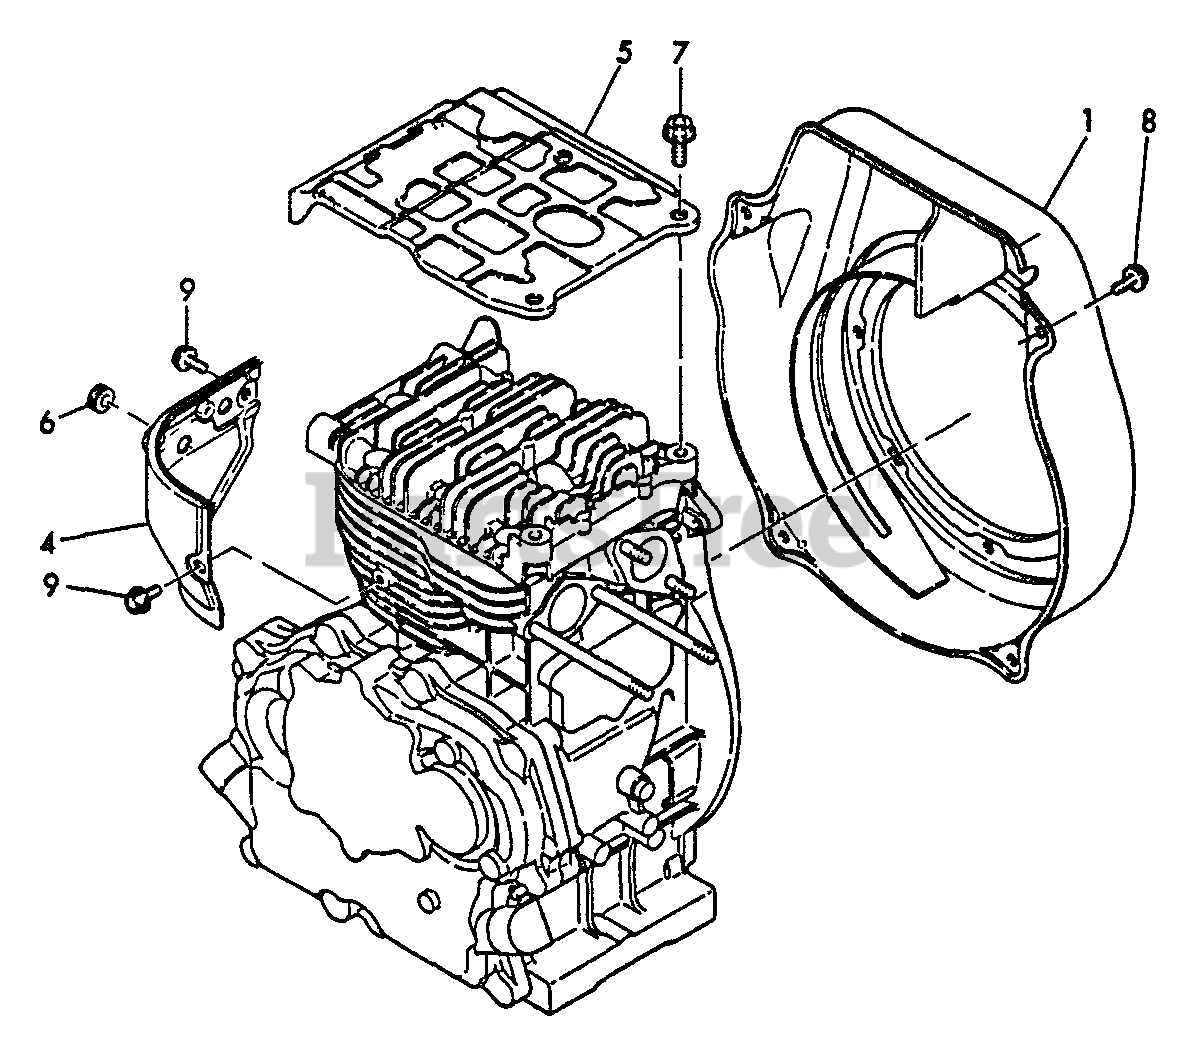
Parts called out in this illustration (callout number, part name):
1	COVER, FAN - INNER
4	SHIELD, CYLINDER
5	COVER, HEAD
6	GROMMET
7	BOLT - 8×20 -- PLATED
8	BOLT - 6×8 -- PLATED
9	BOLT - 6×8 -- PLATED
